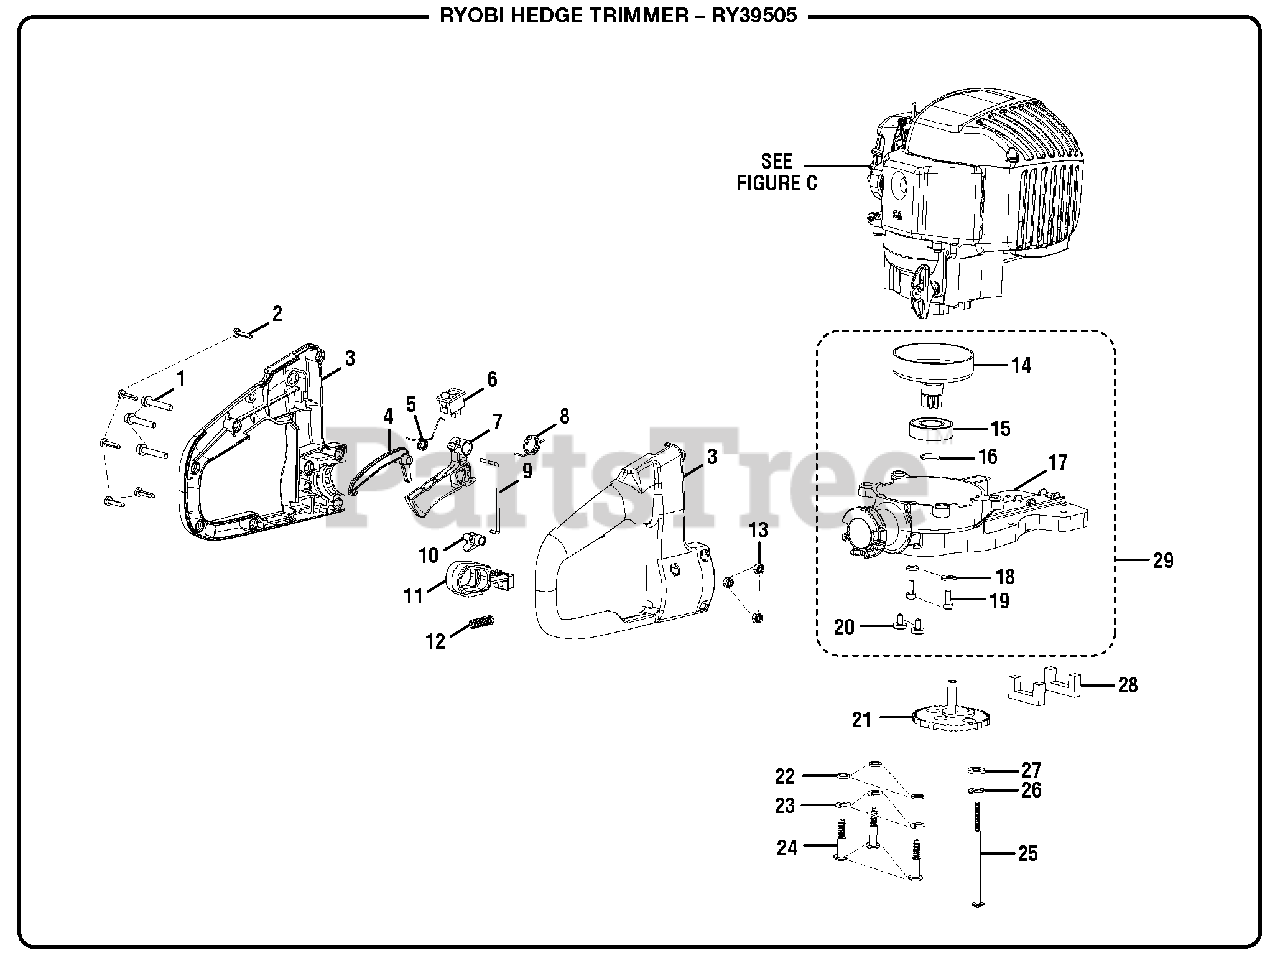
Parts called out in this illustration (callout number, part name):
1	Screw (M5 x 28 mm)
2	Screw (M4 x 18 mm)
3	Rear Handle Housing Assembly
4	Interlock Level
5	Trigger Lock Spring
6	Switch
7	Throttle Trigger
8	Trigger Spring
9	Lock Level
10	Rotate Level
11	Rotate Lock Puller
12	Rotate Lock Spring
13	Hex Nut (M5 x 0.8 in.)
14	Clutch Drum Assembly
15	Ball Bearing (6003ZZ)
19	Screw (M4 x 11 mm)
20	Screw (M4 x 12 mm)
21	Big Gear Assembly
23	Spring Washer
24	Screw (M5 x 27 mm)
25	Screw (M4 x 80 mm)
26	Spring Washer
28	Felt Seal
29	Gear Box Assembly
